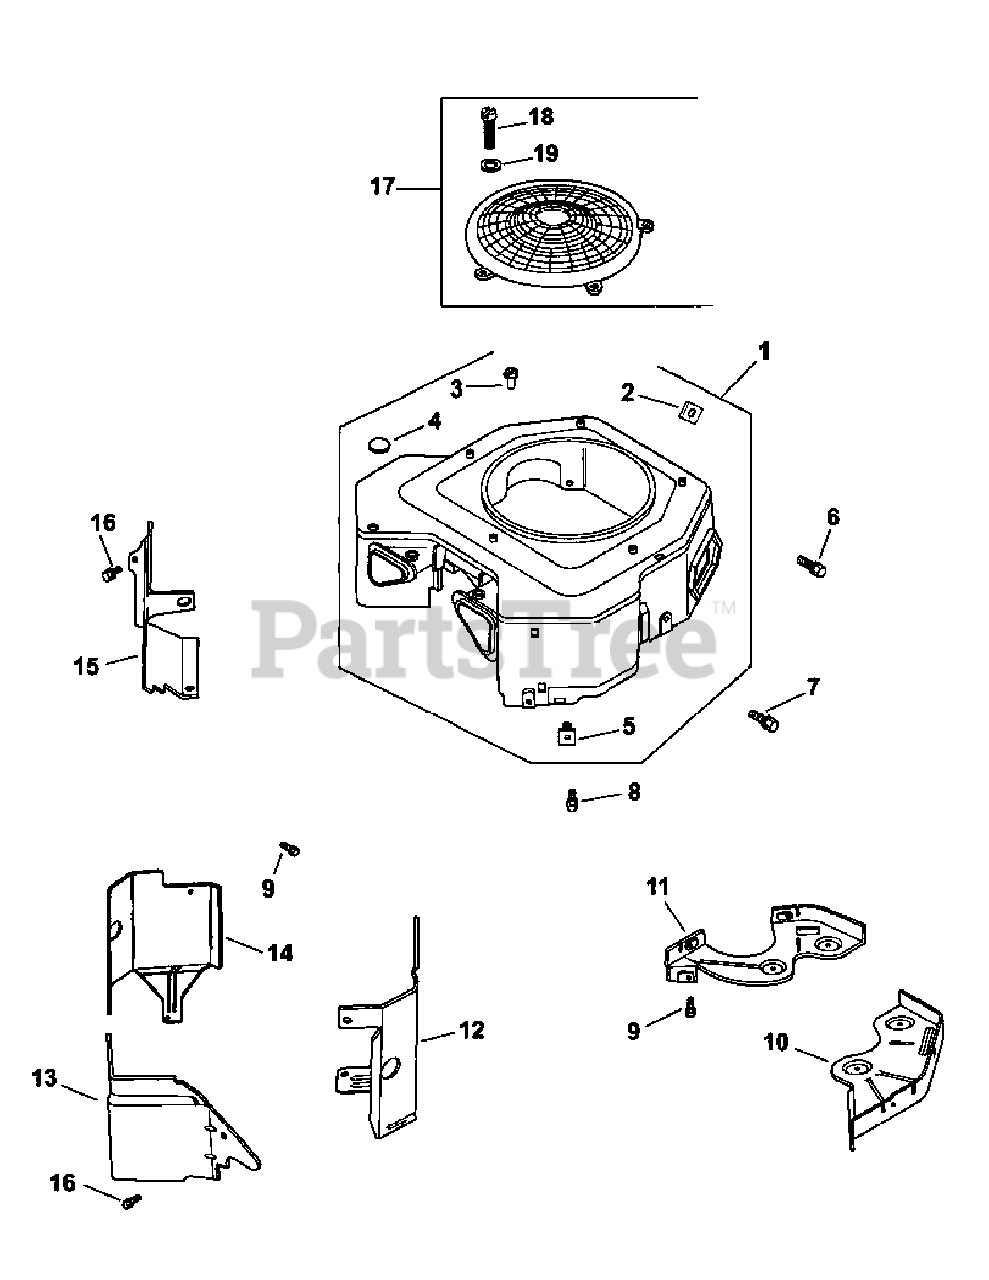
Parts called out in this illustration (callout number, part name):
1	Blower Housing
4	Button Plug (9/16")
6	Hex Flange Screw (M5 x .8 x 16)
7	Hex Flange Screw (M5 x .8 x 16)
8	Hex Flange Screw (M5 x .8 x 20)
9	Hex Flange Screw (M6 x 1.0 x 16)
10	Backing Plate #2 Side
11	Backing Plate #1 Side
12	Cylinder Barrel Baffle # 2 Side
13	Valley Baffle # 2 Side
14	Cylinder Barrel Baffle # 1 Side
15	Valley Baffle # 1 Side
16	Hex Flange Screw (M5 x .8 x 10)
17	Fixed Guard Kit
19	Pan Head Screw
